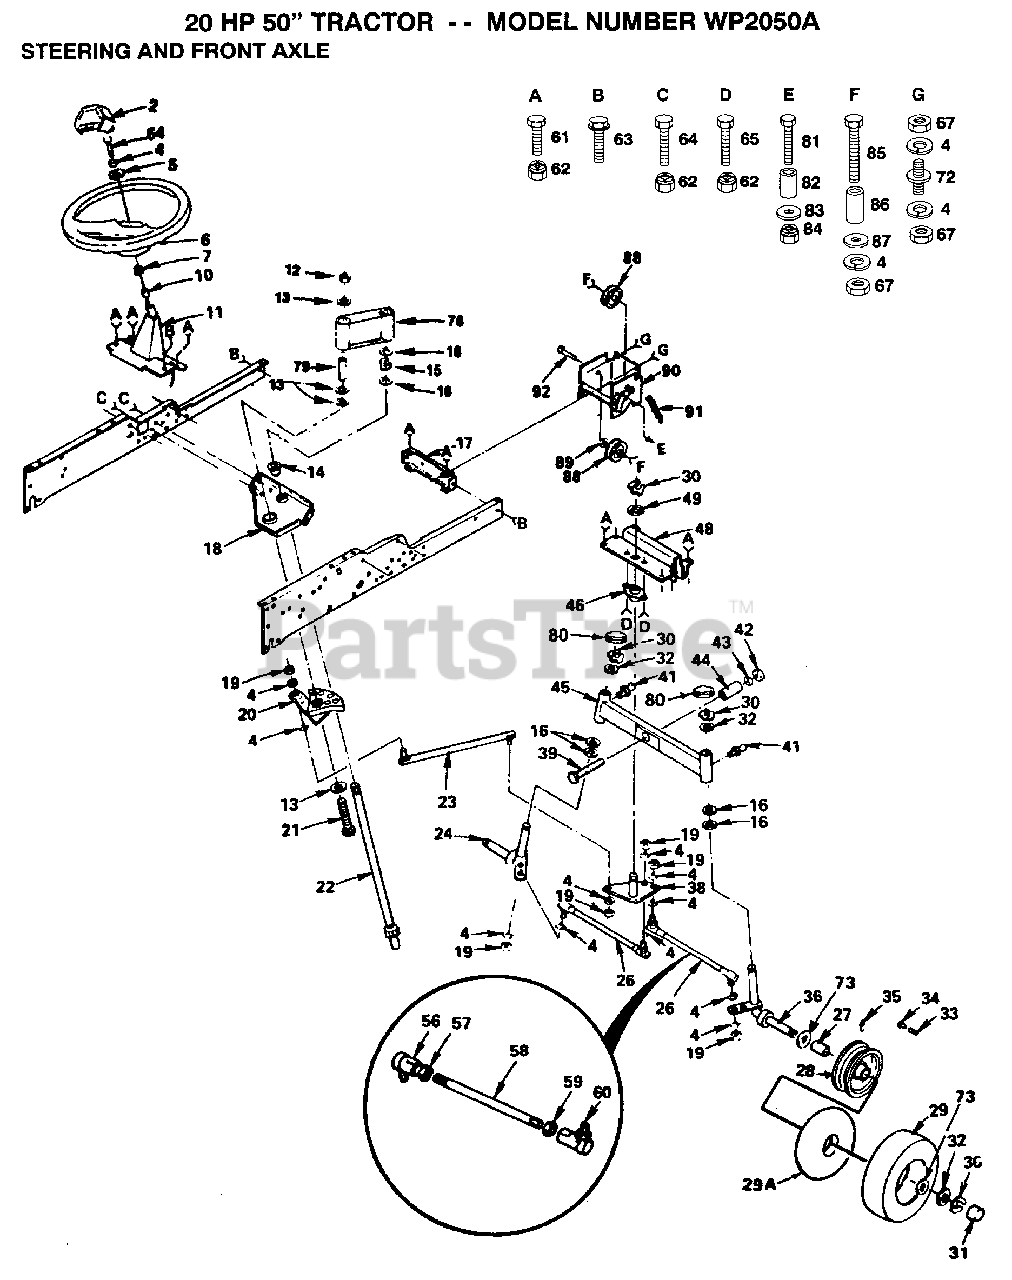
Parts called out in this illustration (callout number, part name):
2	"INSERT,STR WHEEL"
4	LOCKWASHER
5	WASHER T
7	ADAPTER LT
10	"T, BEARING"
11	SUPPORT ASSY T
12	NUT LTV
13	WASHER GT
14	"FLANGE GT, BEAR."
15	KLIP RING
16	WASHER .T
17	FRAME BRACKET GT
20	SECTOR T
21	BOLT T
22	SHAFT STEERING GT
23	LINK.DRAG.T
27	"FLANGE, BEARING"
29A	TUBE.16X6.5/7.5-8
30	RING
31	HUB CAP
32	WASHER
33	VALVE CAP
34	VALVE STEM LT
35	FITTING LT
38	"T, BELLCRANK"
39	BOLT
41	ZERK M
42	NUT X
43	WASHER
48	AXLE BRACKET T
49	WASHER
57	NUT
58	ROD TIE
59	NUT
63	SCREW
64	BOLT
65	BOLT
67	NUT.HEX.3/8-16UNC
73	WASHER
76	COLLAR
79	TUBE T
80	CAP
82	SPLIT SPACER YTV
83	WASHER
85	BOLT
86	BUSHING LT
87	WASHER
88	IDLER-INSIDE T
89	WASHER T
90	IDLER BRKT T
91	SPRING
